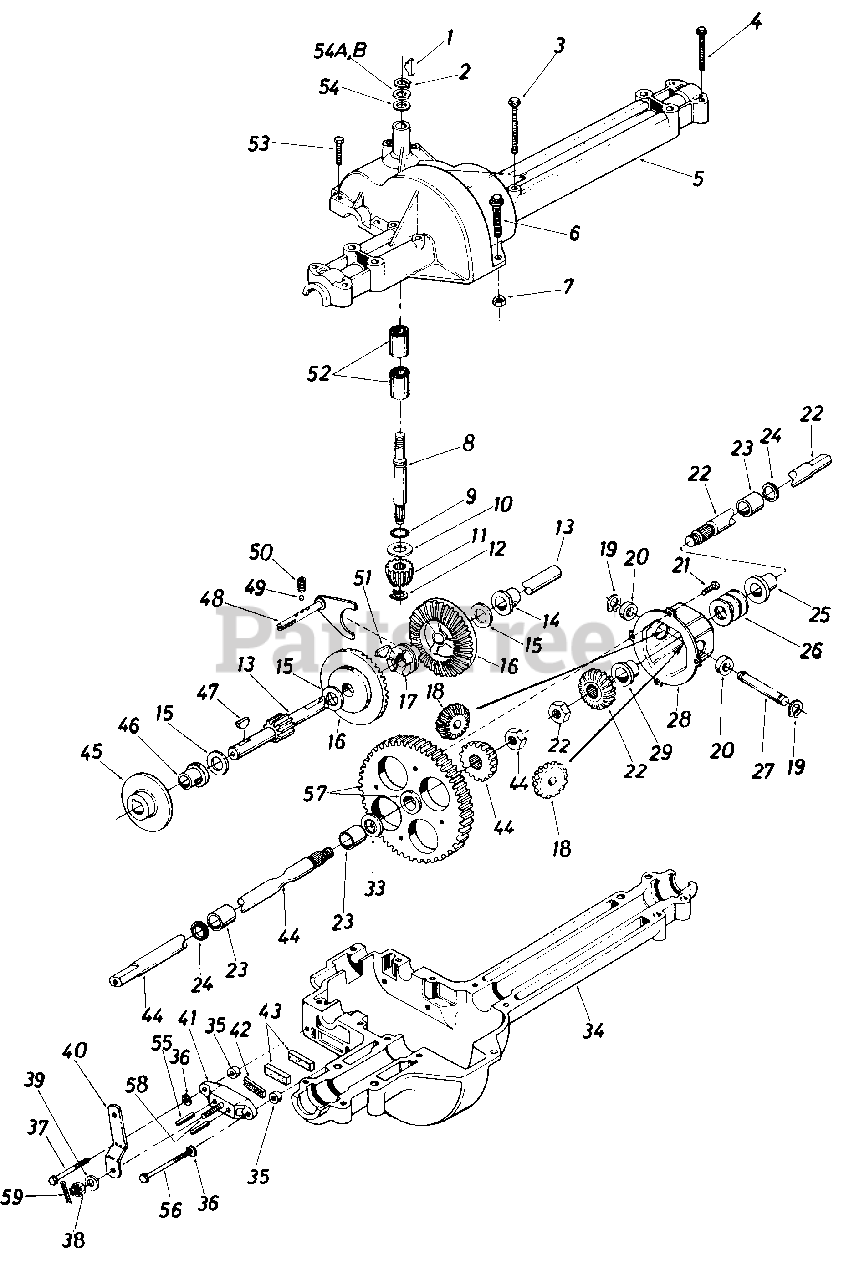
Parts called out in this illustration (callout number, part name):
1	#4 Hi-Pro Key 3/32 x 518" Dia.
2	Snap Ring .625" Shaft
3	Hex Bolt 1/4-20 x 1.75" Lg.
4	Hex Bolt 5/16-18 x 2.5"
5	Upper Housing
6	Hex Fl-Bolt 1/4-20 x .88" Lg.
7	Hex Nut 1/4-20 Thd.
8	Input Shaft
9	Square Seal 5/8" I.D.
10	Thrust Washer 5/8" I.D. x 1.25 O.D.
11	Pinion Input 14T
12	Retaining Ring 7/16" Ext.
13	Drive Shaft
14	Flange Brg. 5/8" I.D. x 3/4" Lg.*
15	Fl-Wash.
16	Bevel Gear 42T
17	Clutch Collar
18	Miter Gear 15T (H.D.)
19	Snap Ring
20	Thrust Bearing 1/2" I.D. x 1.0" O.D.
21	Pan Head Scr. 1/4-20 x .50" Lg. w/Patch
22	Axle R.H. Ass'y.-Kit
23	Sleeve Bearing 3/4" I.D. x 1.0" Lg.
24	Oil Seal 3/4" I.D.
25	Flange Bearing 3/4" I.D. x 15/16" Lg.
26	Fl-Wash. .760" I.D. x 1.49" O.D.
27	Cross Shaft
28	Differential Housing Ass'y.
33	Fl-Wash. .760" I.D. x 1.49" O.D.
34	Lower Housing
35	Spacer .53" O.D. x 3/8" Lg.
36	L-Wash. 1/4" I.D.
37	Hex Bolt 1/4-20 x 1.50" Lg. (Grade 5)
38	Castle Nut 5/16-24 Thd.
39	Fl-Wash. .344" I.D. x .875" O.D.
40	Actuating Arm
41	Brake Yoke
42	Puck Plate
43	Brake Puck
44	Axle L.H. Ass'y.-Kit
45	Brake Disc
46	Flange Bearing 5/8" I.D. x 15/16" Lg.
47	Woodruff Key 3/16 x 5/8 HT
48	Shift Fork Ass'y.
49	Ball Detent .250" Dia.
50	Spring Detent
51	#9 Hi-Pro Key 3/16" x 3/4" Dia. HT
52	Needle Brg. 5/8" I.D. x 1/2" Lg.
53	Hex Bolt 1/4-20 x 1.00" Lg.
54	Fl-Wash. 5/8" I.D. x .030
54A	Fl-Wash. 5/8" I.D. x .040
54B	Fl-Wash. 5/8" I.D. x .020
55	Actuating Pin 5/16" Dia.
56	Hex Bolt 1/4-20 x 2.50" Lg. (Grade 5)
57	Differential Gear 72T Ass'y. w/ Bearing
58	Sq. Hd. Bolt 5/16-24 Thd.
59	Cotter Pin 3/32" Dia. x .50" Lg.
